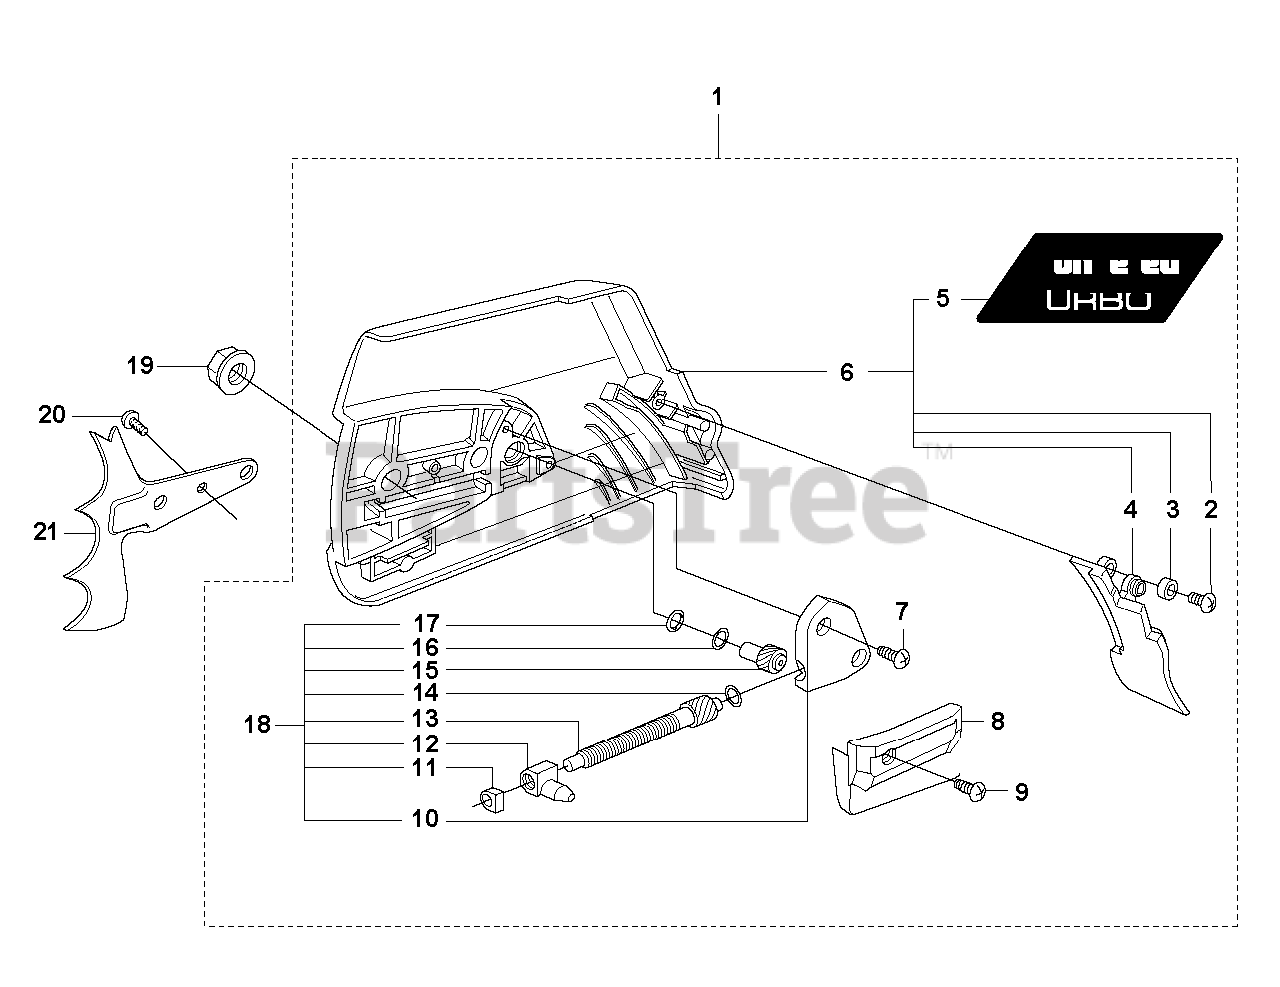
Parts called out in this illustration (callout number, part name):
1	CLUTCH COVER
2	SCREW
3	WASHER
4	PROTECTOR
5	DECAL
6	CLUTCH COVER
7	SCREW
8	GUIDE
9	SCREW
10	COVER
11	SLEEVE
12	COUPLING
13	WORM SCREW / ADJUSTER
14	WASHER
15	RP ADJUSTER
16	WASHER
17	O-RING
18	KIT-CHAIN TENSIONER
19	NUT M8 FLANGE
21	FELLING DOG
